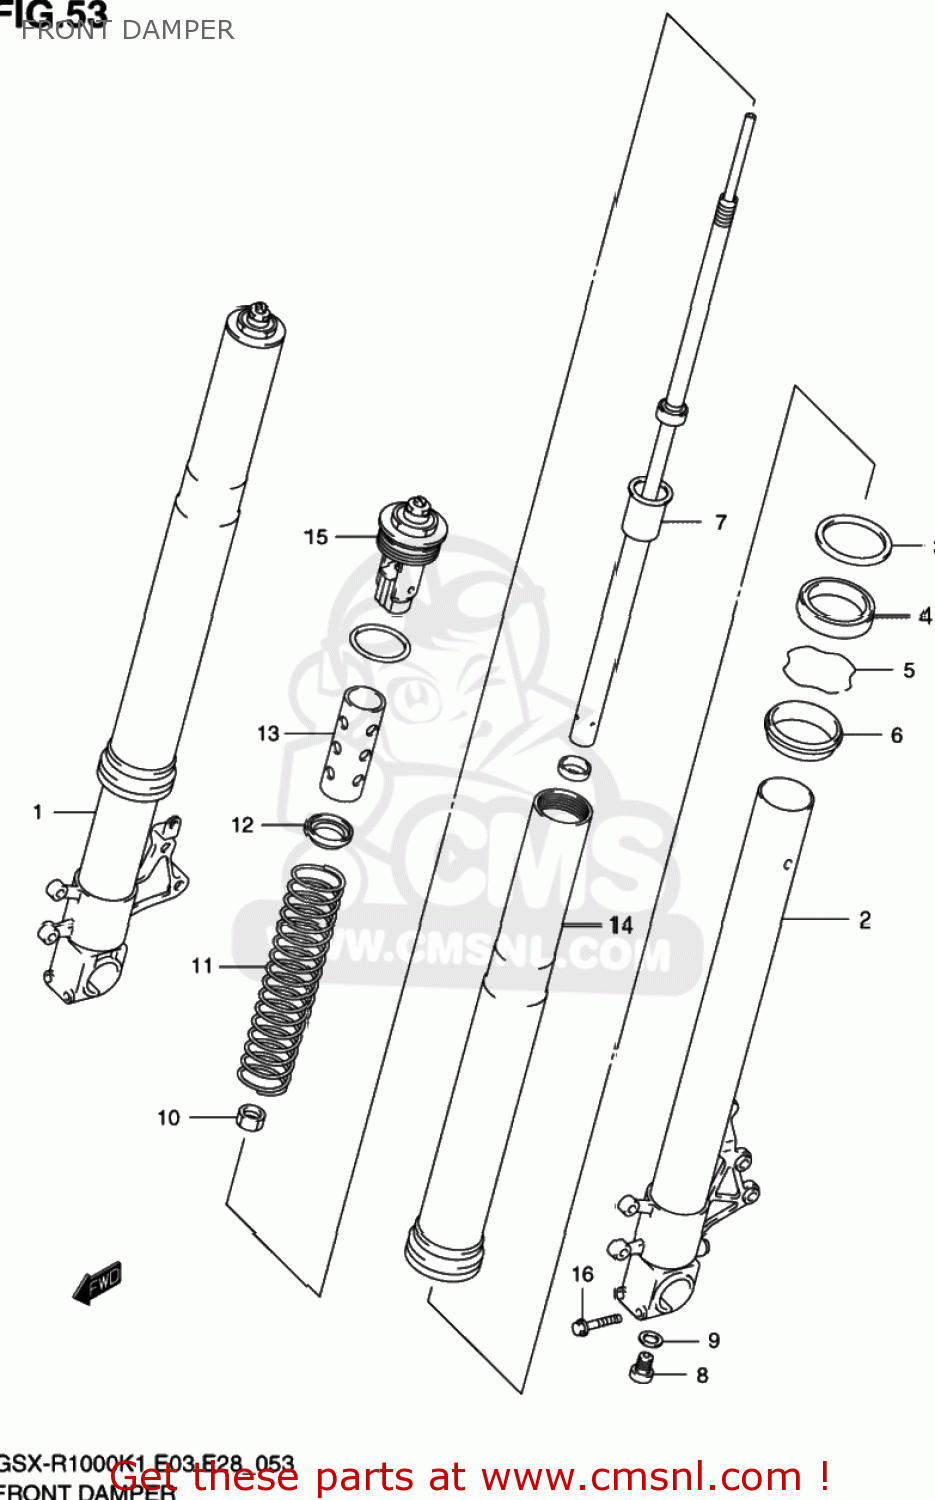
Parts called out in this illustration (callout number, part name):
1	TUBE,INNER,R
2	TUBE,INNER,L
3	WASHER
4	SEAL,OIL
5	RING,STOPPER
6	SEAL,DUST
7	CYLINDER
8	BOLT,OIL LOCK PIECE,12X22
9	GASKET,CYLINDER (NAS)
10	NUT
11	SPRING,FR
12	GUIDE,SPRING
13	SPACER,SPRING
14	TUBE,OUTER
15	CAP,FR FORK
16	BOLT
